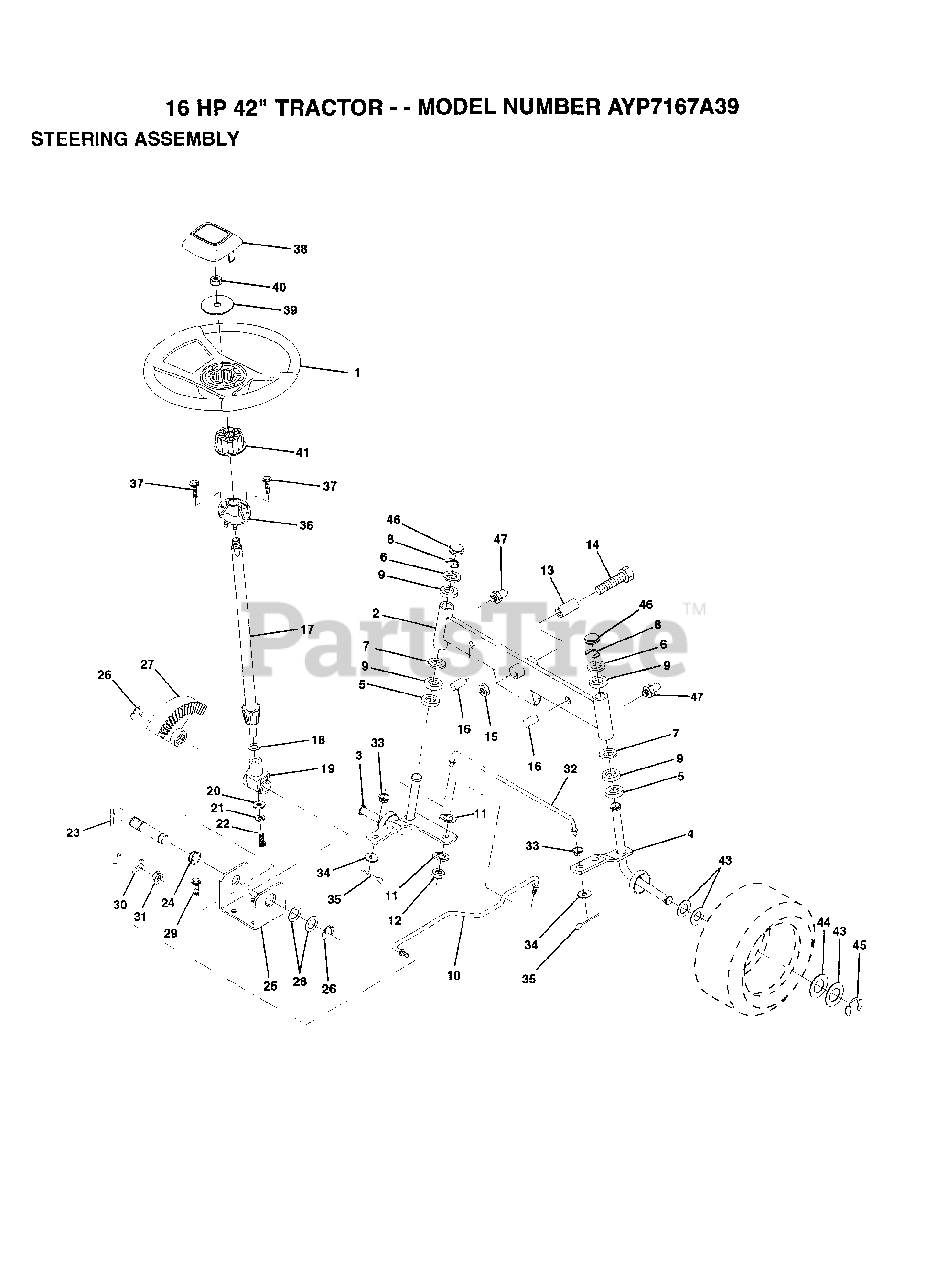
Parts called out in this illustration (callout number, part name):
3	SPINDLE LH
4	SPINDLE RH
5	WASHER .T
6	WASHER
7	WASHER
8	RING
9	COL. SRTG. BEAR.
11	LOCKWASHER
13	BEARING
14	BOLT HEX 5/8-11
15	"NUT-LOC,FLANGE LT"
16	AXLE PIN
17	STEERING SHAFT
18	THRUST WASHER
19	SUPPORT.SHAFT
21	LOCKWASHER
22	"SCREW,SPECIAL"
24	NYLINER T
25	"BRKT,STEERING"
26	RING
27	GEAR SECTOR
28	WASHER .T
29	SCREW
30	LOCKWASHER
32	TIE ROD
33	BUSHING.DRAGLINK
34	WASHER
35	COTTER PIN
38	ST WHL INSERT CAP
39	WASHER
41	ADAPTER LT
43	WASHER
44	WASHER
45	RING
46	CAP
47	ZERK M
